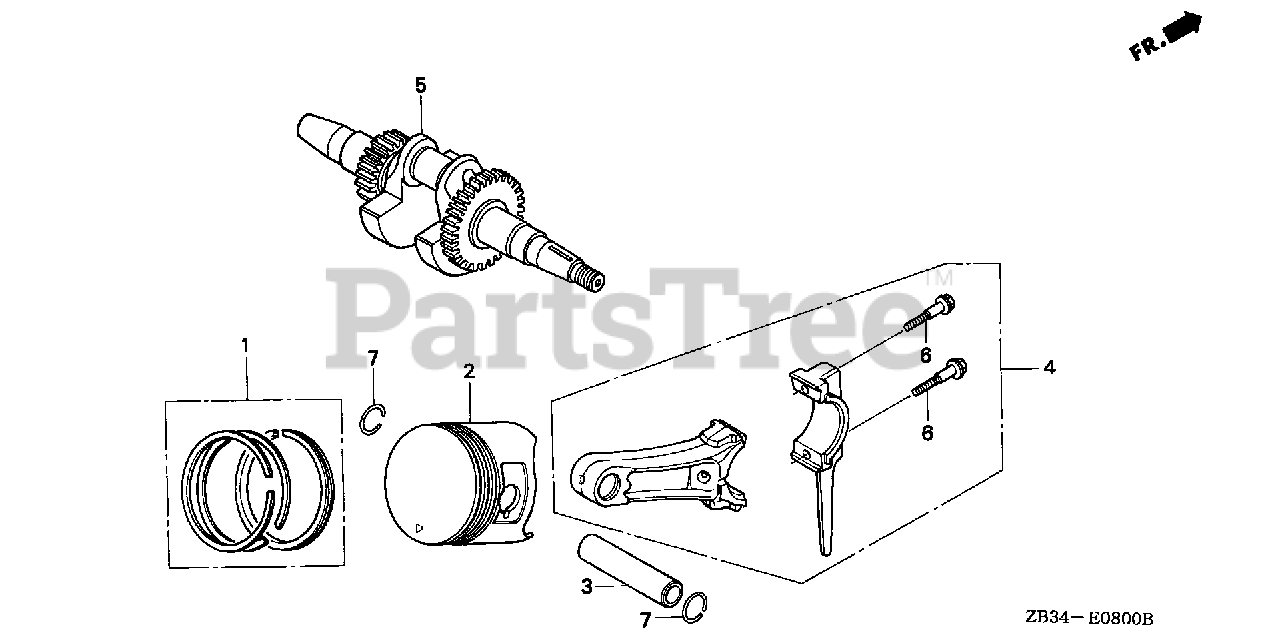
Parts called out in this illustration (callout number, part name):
1	RING SET, PISTON (STD) (TEIKOKU)
1	RING SET, PISTON (STD.) (TEIKOKU)
1	RING SET, PISTON (STD.) (NIPPON)
1	RING SET, PISTON (0.25) (TEIKOKU)
1	RING SET, PISTON (0.25) (NIPPON)
1	RING SET, PISTON (0.50) (TEIKOKU)
1	RING SET, PISTON (0.50) (NIPPON)
1	RING SET, PISTON (0.75) (TEIKOKU)
1	RING SET, PISTON (0.75) (NIPPON) (NOT AVAILABLE)
1	RING SET, PISTON (0.75) (NIPPON)
2	PISTON (STD)
2	PISTON (0.25)
2	PISTON (0.50)
2	PISTON (0.75)
3	PIN, PISTON
4	ROD ASSY., CONNECTING (0.25 LOWER SIZE)
4	ROD ASSY., CONNECTING (STD)
4	ROD ASSY., CONNECTING (TH)
5	CRANKSHAFT
6	BOLT, CONNECTING ROD
7	CLIP, PISTON PIN (18MM)
